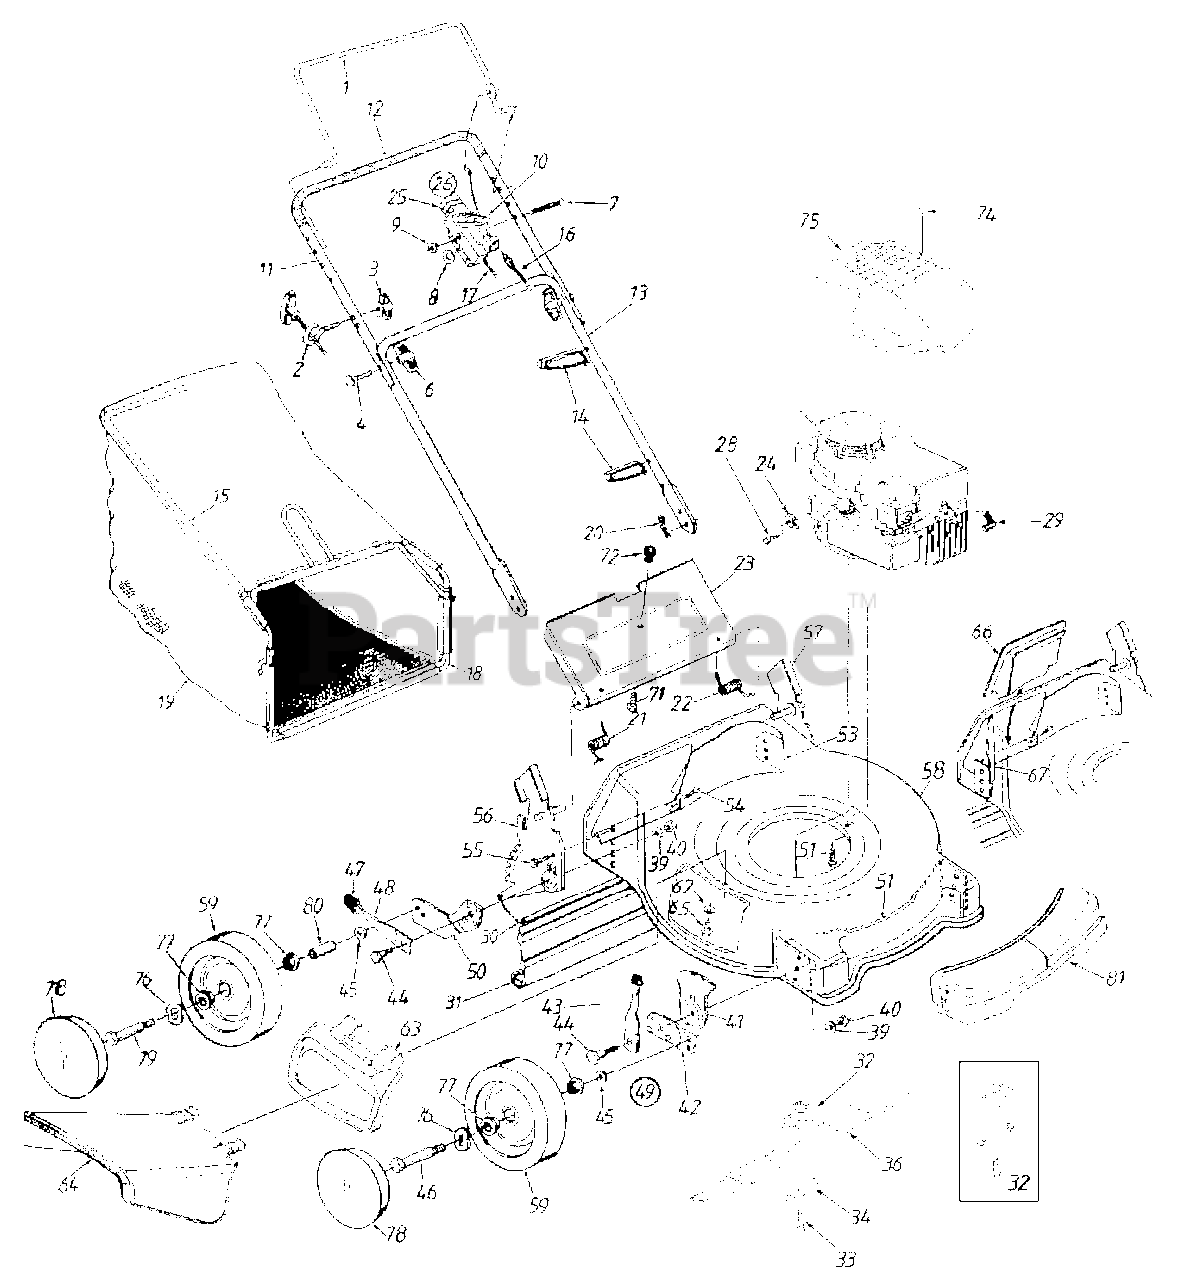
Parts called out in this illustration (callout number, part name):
1	Control Handle Assembly
3	Handle Knob 1/4-20 Thd.
4	Curved Hd. Bolt 5/16-18 x 2"
6	Hand Knob
7	Oval C-Sunk Mach. Scr.
8	Spring Washer
9	Hex Lock Nut
10	Throttle Lever
14	Cable Tie
16	Control Cable
17	Throttle Control Wire
20	Internal Cotter Pin
21	Door Spring-R.H.
22	Door Spring-L.H.
25	Throttle Body
26	Throttle Box Comp.
28	Hx Wash Hd Scr #10-32 x .62
29	Spark Plug Boot
30	Wire Rod
31	Rear Flap
32	Blade Adapter Kit
33	Hex Bolt 3/8-24 x 1.5"
34	Blade Bell Support
36	Mulching Blade 21"
39	Bell Washer
40	Hex Nut 3/8-16 Thd.
41	Height Adj. Plate
43	Spring Lever Ass'ly w/Knob
44	Shoulder Bolt
45	Bell Washer .38" I.D. x .88"
46	Front Axle Bolt
47	Spring Lever Knob
49	Height Adj. Assy-R.H.
54	Torx Mach. AB-Tap Scr. 1/4 x .62"
55	Hx Lk. Wash Hd. AB-Tap Scr.
59	Wheel Assembly Comp.
62	Bell Washer 1/4" I.D.
63	Hinged Mulching Plug
64	Chute Deflector
65	Hx Self-Tap. Scr. 1/4-20 x .5
71	Truss Scr. #10-24 x .38
72	Knob: Chute Door
74	Hi-Lo Scr. #10 x 1.25
75	XTL Gray Shroud
76	Wave Washer
77	Ball Bearings
78	Hub Cap: Radial Spoke Gray
79	Rear Axle Bolt
80	Spacer
81	Cover: Front Deck Gray
